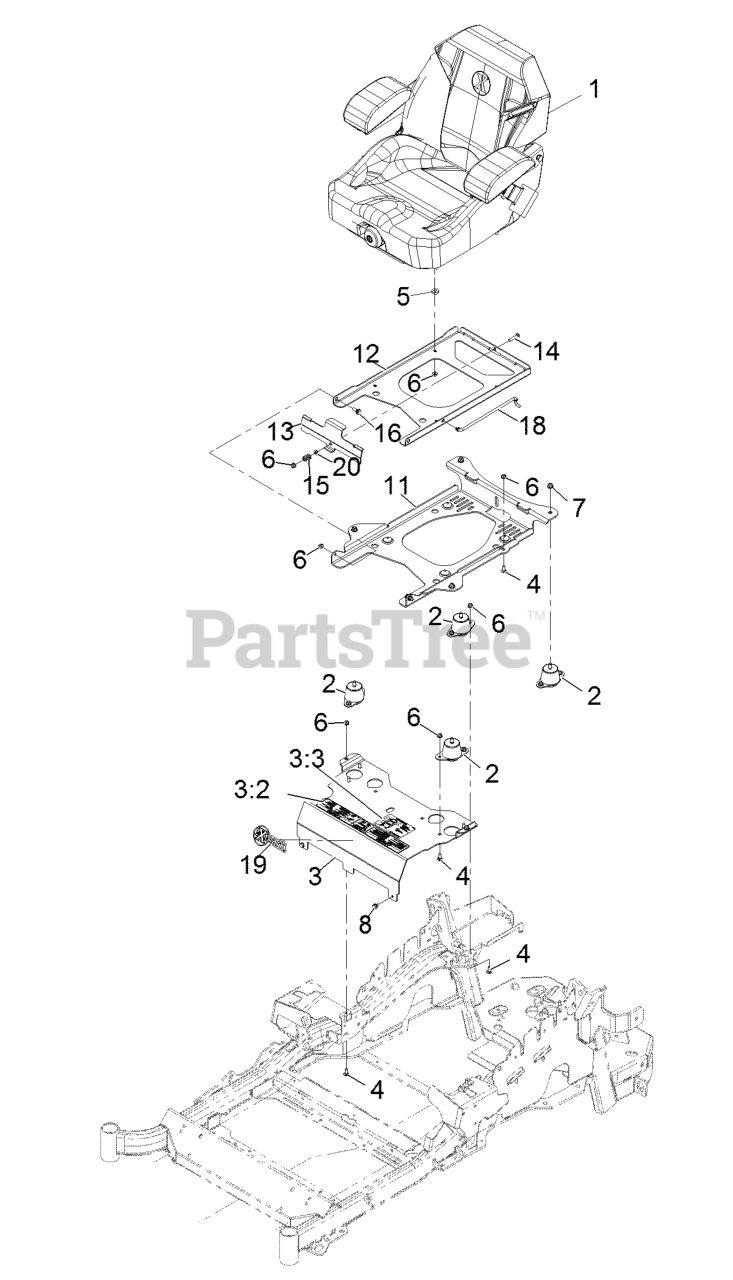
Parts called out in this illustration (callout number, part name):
1	KIT-SUSPENSION SEAT
2	ISOLATOR-SEAT
3	MOUNT-SEAT
3:2	DECAL-CONSOLE
3:3	DECAL-SERVICE AID
4	SCREW-CARR
6	NUT-HF, NI
7	NUT-HF, NI
11	PLATE-TILT, SEAT SUPPORT
12	PLATE-FRAME, SEAT
13	PLATE-LATCH, SEAT
14	BOLT-CARR
15	SPRING-COMPRESSION
16	SCREW-SHOULDER
18	ROD-PROP
20	WASHER-PLAIN
